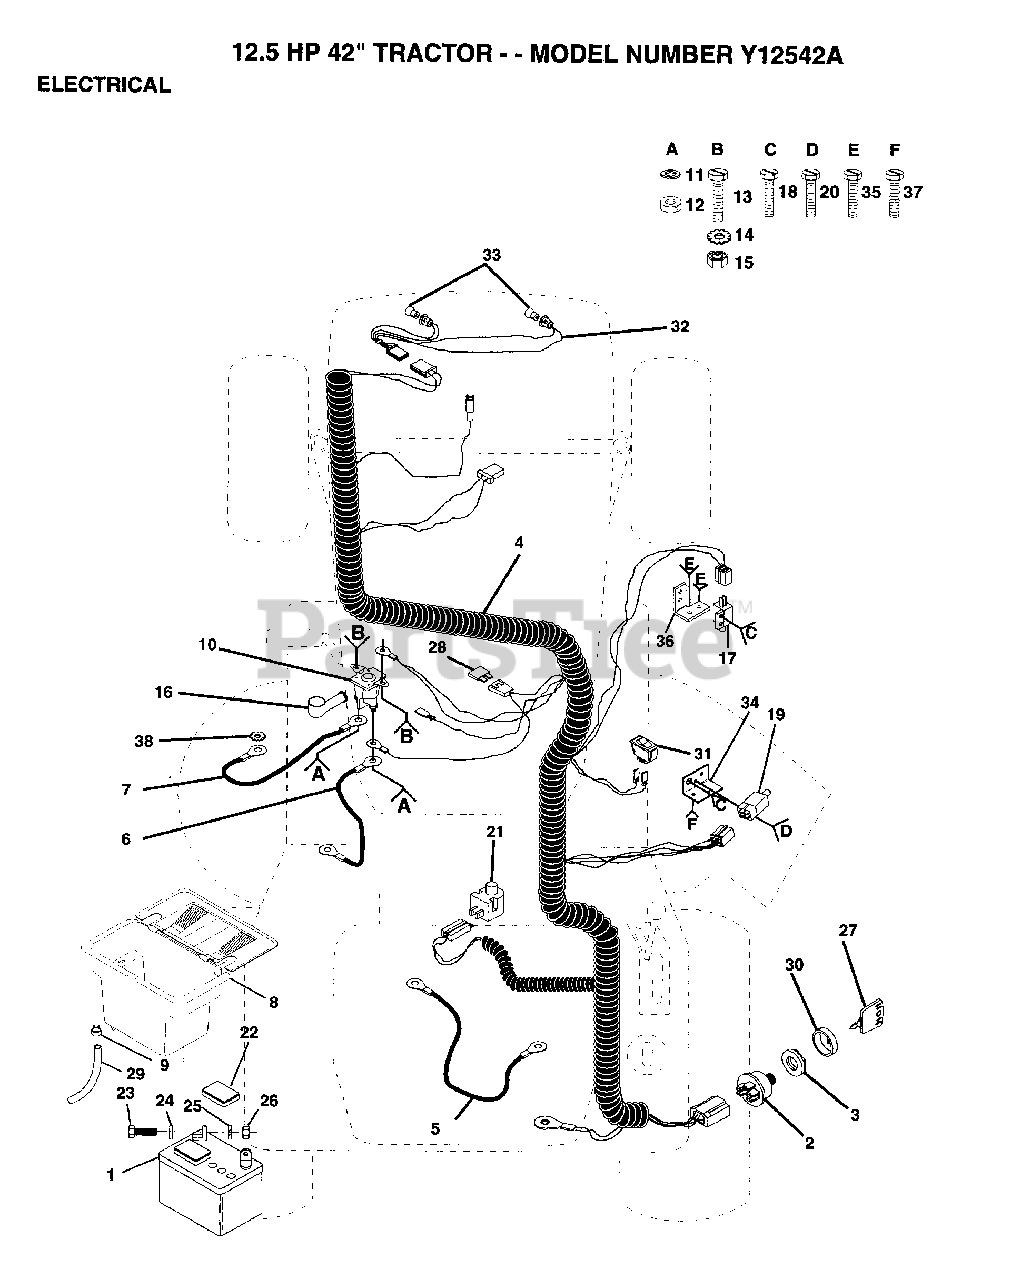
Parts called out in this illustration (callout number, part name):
3	NUT IGNITION
5	CABLE T
7	"CABLE T, BATTERY"
9	HOSE CLAMP T
12	NUT
13	BOLT
15	NUT
17	SWITCH INTERLOCKT
18	SCREW
19	SWITCH-INTER. GT
20	SCREW
21	SWITCH SEAT
22	"CAP,BATTERY "
23	BOLT LT
24	WASHER
25	LOCKWASHER
27	KEY
28	FUSE HYT
29	TUBE T
31	SWITCH LT
34	SWITCH BRACKET
35	SCREW
36	BRACKET LT
37	SCREW
38	LOCKWASHER
